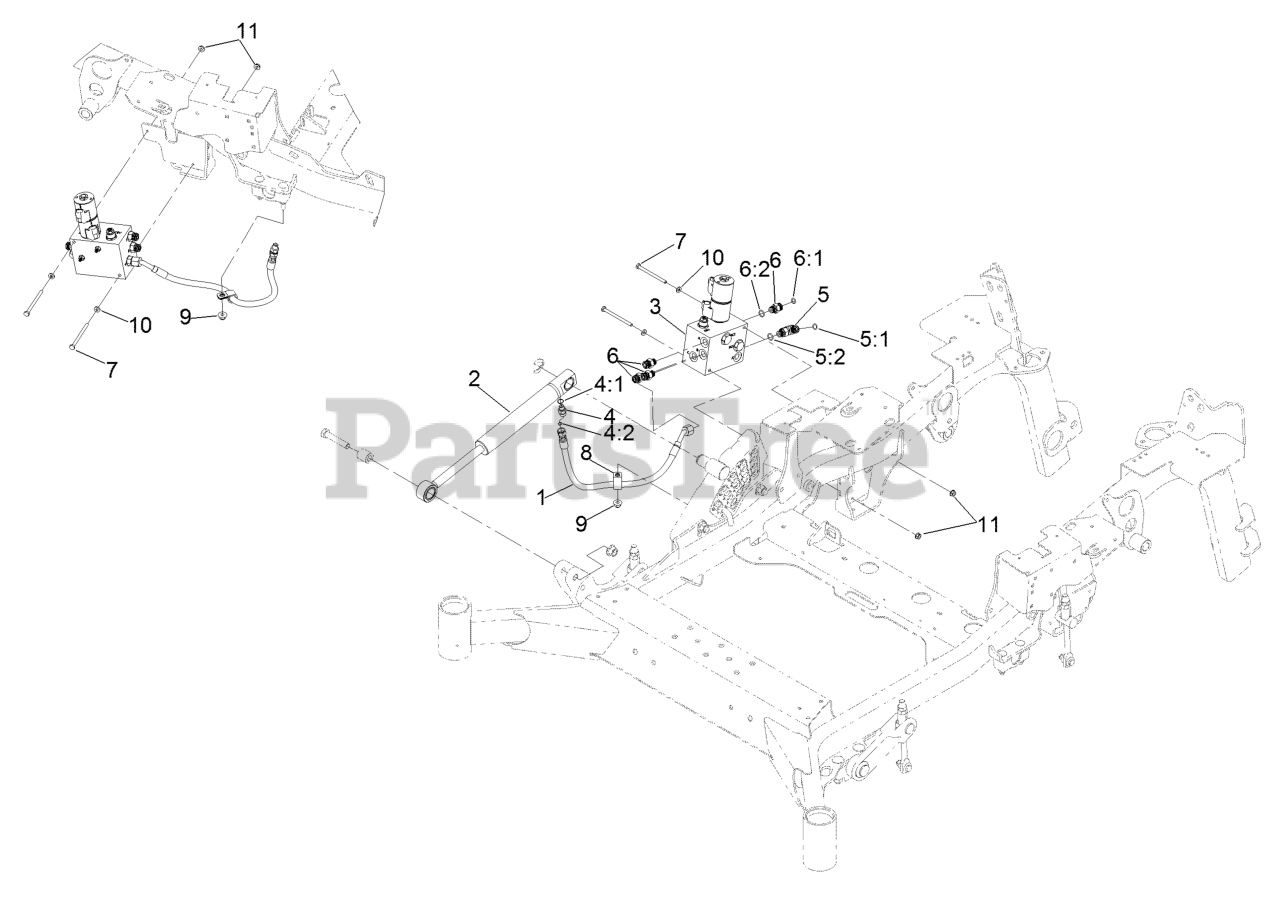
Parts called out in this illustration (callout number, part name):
1	Hose ASM
2	Cylinder-Lift
3	Lift And Fold Valve Assembly
4	Fitting-HYD, Straight
4:1	O-Ring
4:2	O-Ring
5	Fitting-Elbow, 90 DEG
5:1	O-Ring
5:2	O-Ring
6	Fitting-Straight
6:1	O-Ring
6:2	O-Ring
7	Screw-HH
8	Clip-Loom 5/8
9	Nut-Nyloc 3/8-16 Flg
10	Washer-#12 Std
11	Nut-Whizlock 1/4-20
